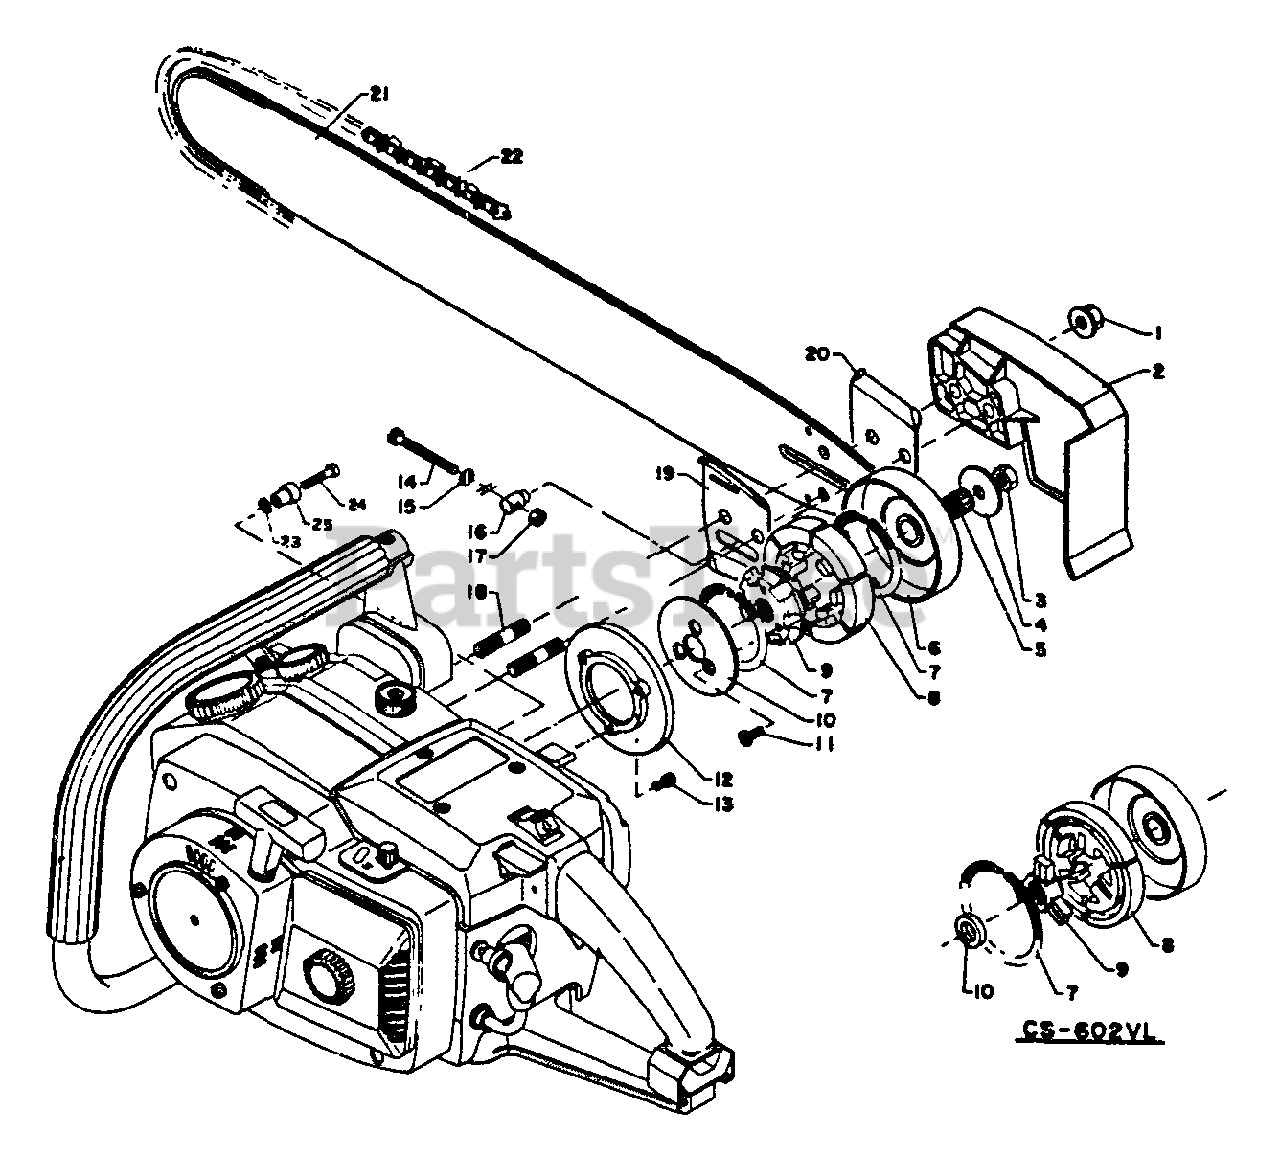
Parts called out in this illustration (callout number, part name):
1	NUT - FLANGE
2	GUARD, SPROCKET
3	LOCKNUT
4	WASHER, CLUTCH
5	BEARING, NEEDLE
6	DRUM, CLUTCH
7	SPRING, CLUTCH
8	SHOE, CLUTCH
8	SPRING, CLUTCH
9	HUB, CLUTCH
10	PLATE, CLUTCH
10	WASHER, CLUTCH
11	SCREW - 5X12
12	SEAL, DUST
13	SCREW - 4X10
14	SCREW, TENSIONER
15	WASHER - 5
16	TENSIONER, CHAIN
17	LOCKNUT - 5
18	STUD, GUIDE BAR
19	PLATE, GUIDE - INNER
20	PLATE, GUIDE - OUTER
21	GUIDE BAR - 60M50
21	GUIDE BAR - 50" (127cm)
22	SAW CHAIN - 72LP-84E
22	SAW CHAIN - 72LP-72E
23	WASHER - 5
24	SCREW - 5X25
25	CATCHER, CHAIN
